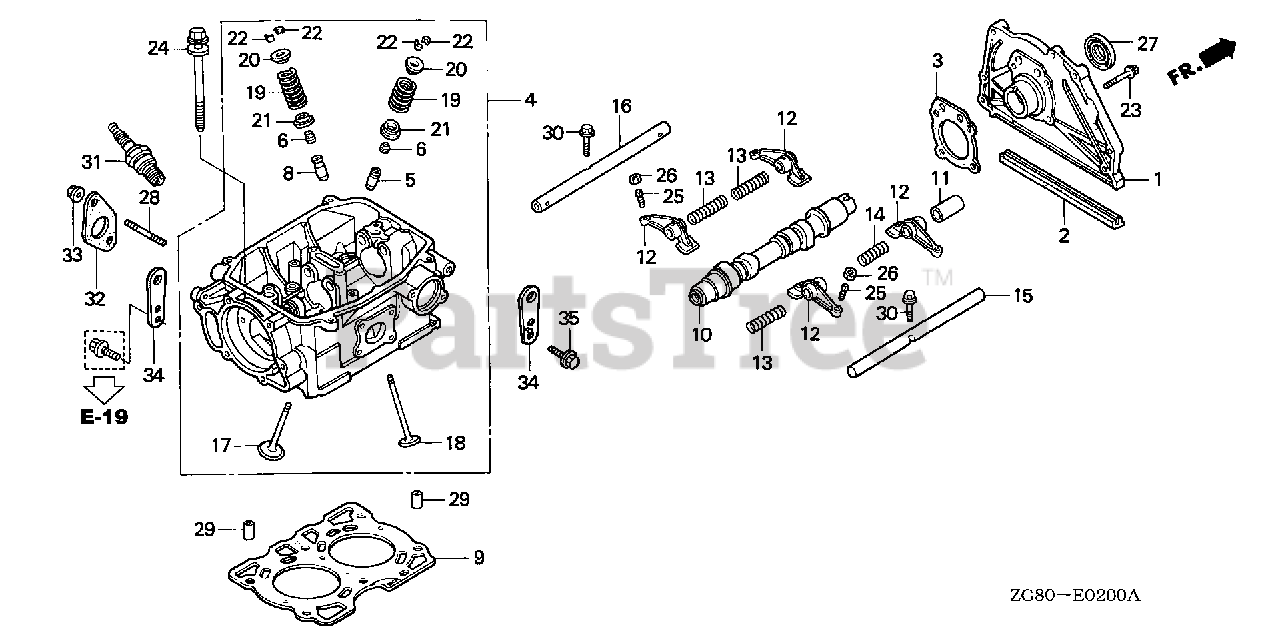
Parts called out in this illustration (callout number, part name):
1	COVER, RR. TIMING BELT
2	GASKET, RR. TIMING BELT COVER
3	GASKET, RR. TIMING BELT COVER
4	CYLINDER HEAD ASSY.
5	GUIDE, VALVE (OVER SIZE)
6	SEAL, VALVE STEM (ARAI)
8	GUIDE, EX. VALVE (OVER SIZE)
9	GASKET, CYLINDER HEAD
10	CAMSHAFT (20PS)
11	COLLAR, ROCKER ARM
12	ARM, ROCKER
13	SPRING, ROCKER ARM A
14	SPRING, ROCKER ARM B
15	SHAFT, IN. ROCKER ARM
16	SHAFT, EX. ROCKER ARM
17	VALVE, IN.
18	VALVE, EX.
19	SPRING, VALVE
20	RETAINER, VALVE SPRING
21	SEAT, VALVE SPRING
22	COTTER, VALVE
23	BOLT, FLANGE (6X30)
24	BOLT-WASHER (10X115)
25	SCREW, TAPPET ADJUSTING
26	NUT, TAPPET ADJUSTING
27	OIL SEAL (28X40X8)
28	BOLT, STUD (8X22)
29	PIN, DOWEL (12X20)
30	BOLT, FLANGE (6X30)
31	SPARK PLUG (BPR5ES-11)
31	SPARK PLUG (W16EPR-U11)
32	GASKET, EX. PIPE
33	NUT, FLANGE (8MM)
